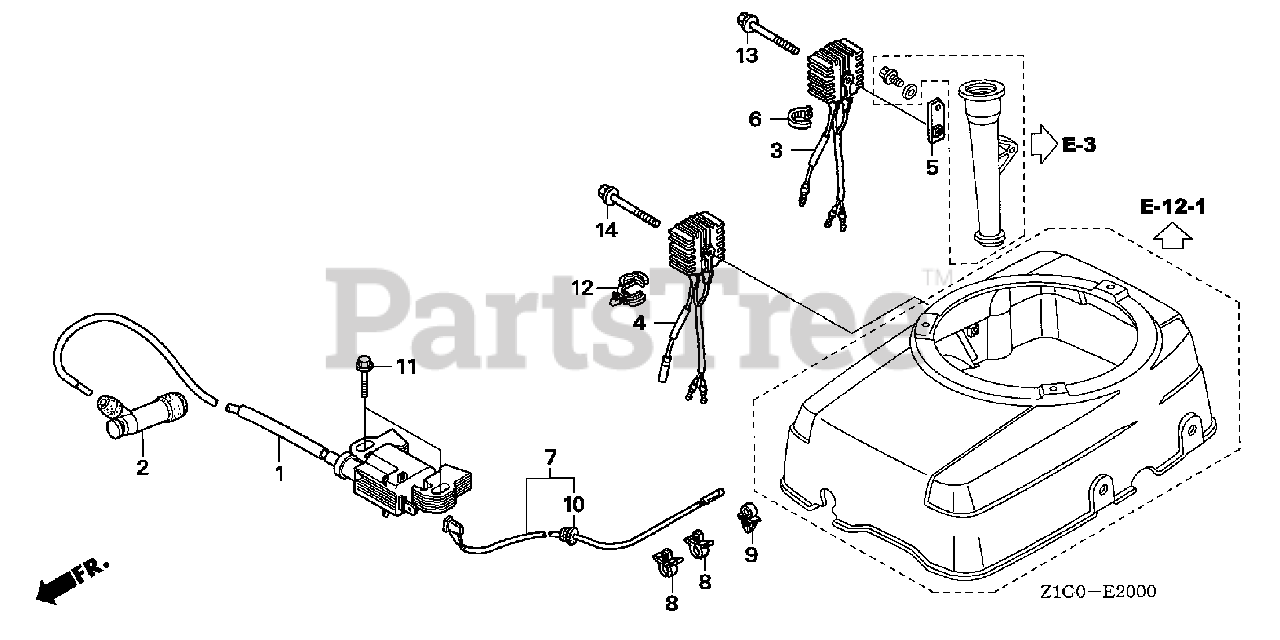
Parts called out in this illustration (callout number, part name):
1	COIL ASSY., IGNITION
2	CAP ASSY., NOISE SUPPRESSOR
4	RECTIFIER ASSY., SILICON
7	WIRE, STOP SWITCH
8	CLIP, BRAKE PIPE (A)
9	HOLDER, WIRE (FASTEX)
10	GROMMET, WIRE CORD
11	BOLT, FLANGE (6X28) (CT200)
12	CLIP, HARNESS
14	BOLT, FLANGE (6X40)
